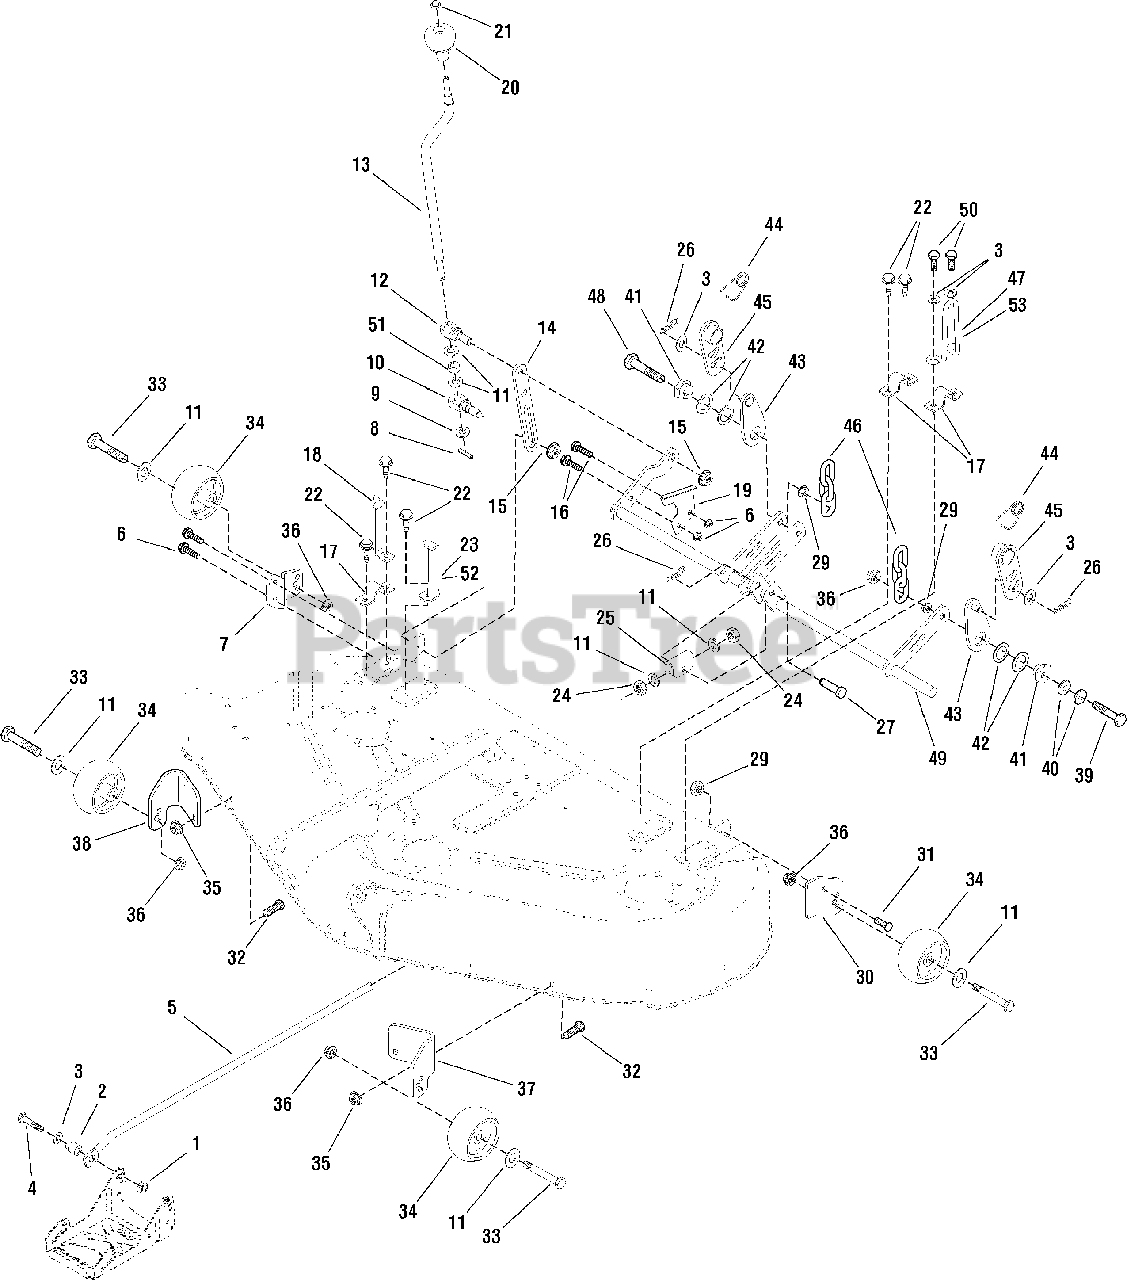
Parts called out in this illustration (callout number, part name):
1	NUT, Locknut, 3/8-16
2	SPACER, 3/8 x 3/4 x 15/16
3	WASHER. 3/8
4	CAPSCREW, Hex 3/8-16 x 1 3/4
5	ROD, Adjustment
6	SCREW, Hex Tapit 3/8-16 x 1
7	SUPPORT, Wheel
8	PIN, Roll
9	WASHER, Detent
10	TRUNNION
11	WASHER, 1/2
12	TRUNNION, Threaded
13	CRANK, Height of Cut
14	STOP, Height
15	NUT, Hex Flange Lock 1/2-13
16	SCREW, Hex Whizlock,Flange 5/16-18 x 3/4
17	STRAP, Rocker Shaft
18	INDICATOR, Height of Cut
19	BRACKET, Height of Cut
20	KNOB
21	NUT, PUSH PAL
22	SCREW, Taptite, 5/16-18 x 3/4
23	BRACKET, Upstop
24	NUT, Hex Jam, 1/2-13
25	TRUNNION
26	CLIP, Hairpin
27	PIN, Clevis
29	NUT, Flange Whiz, 3/8-16
30	SUPPORT, Gauge Wheel
31	BOLT, Carriage, 3/8- 16 x 1
32	BOLT, Carriage, 5/16-18 x 7/8
33	BOLT, Wheel, 3/8-16 x 2.781
34	WHEEL
35	NUT, Hex Whiz Lock, 5/16-18
36	NUT, Hex Nylock, 3/8-16
37	BRACKET, Wheel Gauge
38	BRACKET, Gauge Wheel
39	CAPSCREW, 3/8-16 x 2 1/4
40	WASHER, 3/8
41	NUT, Adjuster
42	WASHER
43	HANGER
44	PIN, Safety
45	HANGER ASSEM, Upper
46	CHAIN, 3 Link
47	UPSTOP, Wire 6-1/4
48	CAPSCREW, 3/8-16 x 3
49	ARM ASSEM, Mower 44"
50	SCREW, Taptite, 5/16-18 x 1 1/4
51	SPACER
52	BRACKET, Upstop
53	UPSTOP,Wire 5-1/4
